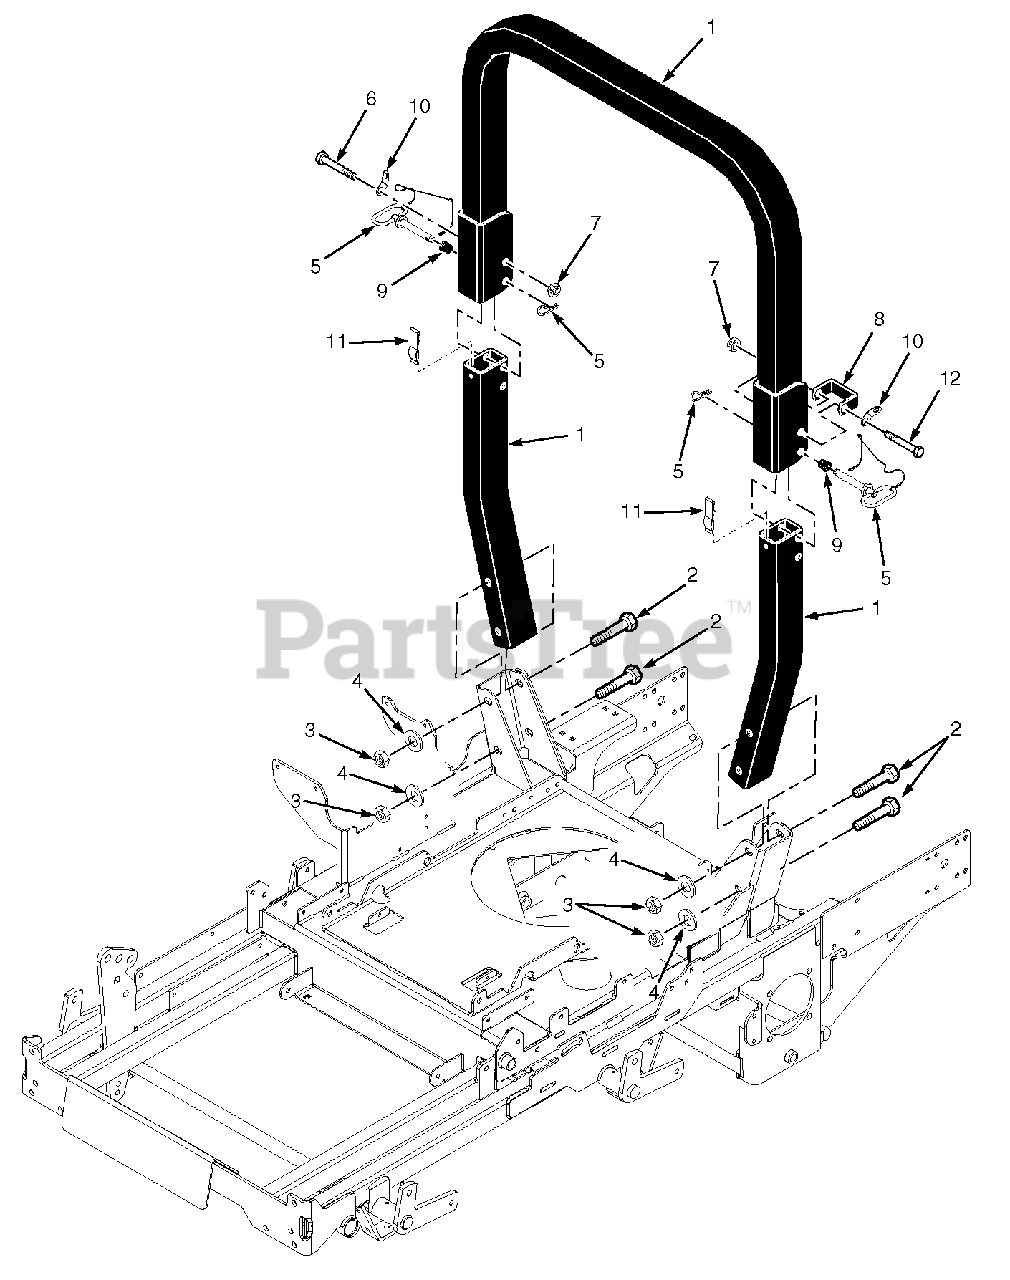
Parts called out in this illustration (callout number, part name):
1	STT, ROPS
2	Bolt, Hex Head 1/2-13 x 4-1/4"
3	Nut, Center Lock 1/2-13
4	Flatwasher, 1/2-.562 x 1.375 x .109
5	Pin Assembly, ROPS Hinge
6	Bolt, Hex Head 1/2-13 x 3-1/4"
7	Nut, Elastic Stop 1/2-13
8	Stop, ROPS
9	Spring, ROPS
10	Clip, ROPS
11	Spring, ROPS
12	Bolt, Hex Head 1/2-13 x 3-3/4"
